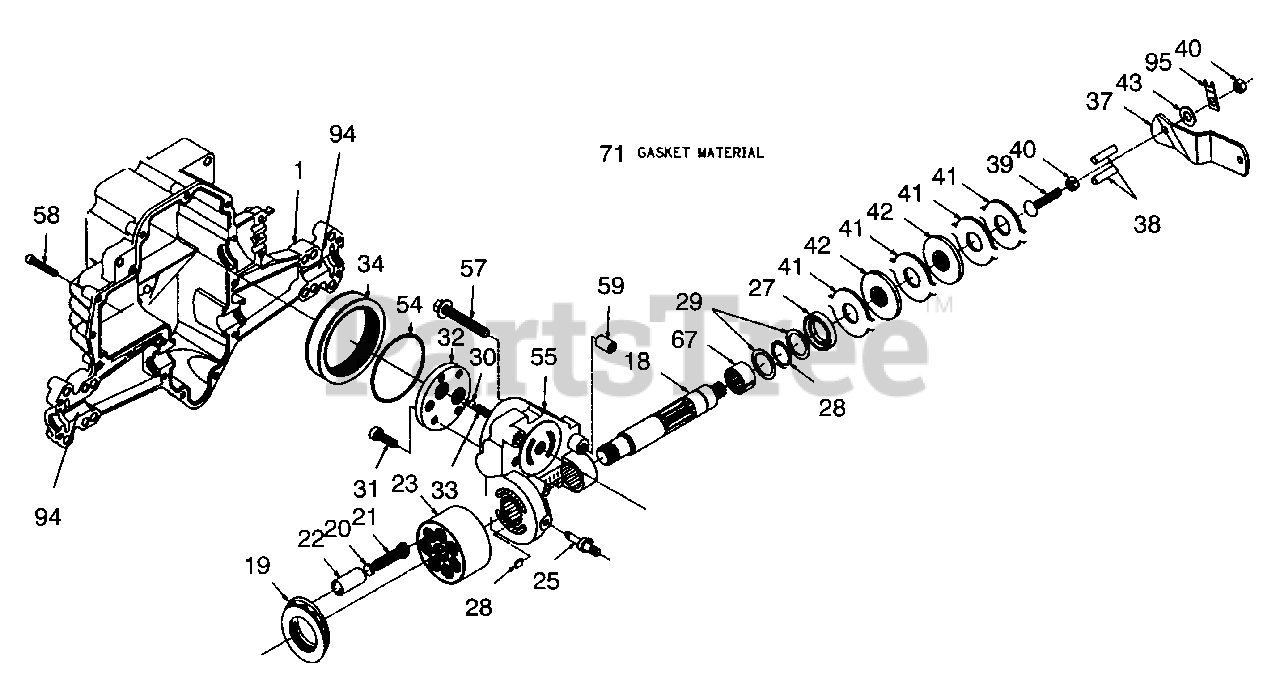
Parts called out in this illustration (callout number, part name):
1	Housing-Lower
18	Shaft-Motor
19	Bearing-Thrust
20	Seat-Piston Spring
21	Spring-Piston
22	Piston
23	Block-Cylinder (Motor)
25	Actuator-Bypass
26	Plate-Bypass
27	Seal-Lip
28	Ring-Retaining
29	Washer
30	Ball
31	Spring-Check Valve (Mod)
32	Plate-Check Valve
33	Socket Hd. Cap Screw
34	Oil Filter Element
37	Lever-Brake
38	Pin-Actuating
39	Bolt
40	Nut-Hex Lock
41	Stator-Brake
42	Rotor-Brake
54	O Ring
55	Center-Section
57	Bolt
58	Bolt
59	Pin
67	Du Bearing
71	Gasket Material (1 oz.)
94	Grease Durina "O" (2.16 oz.)
95	Strap-Locking
